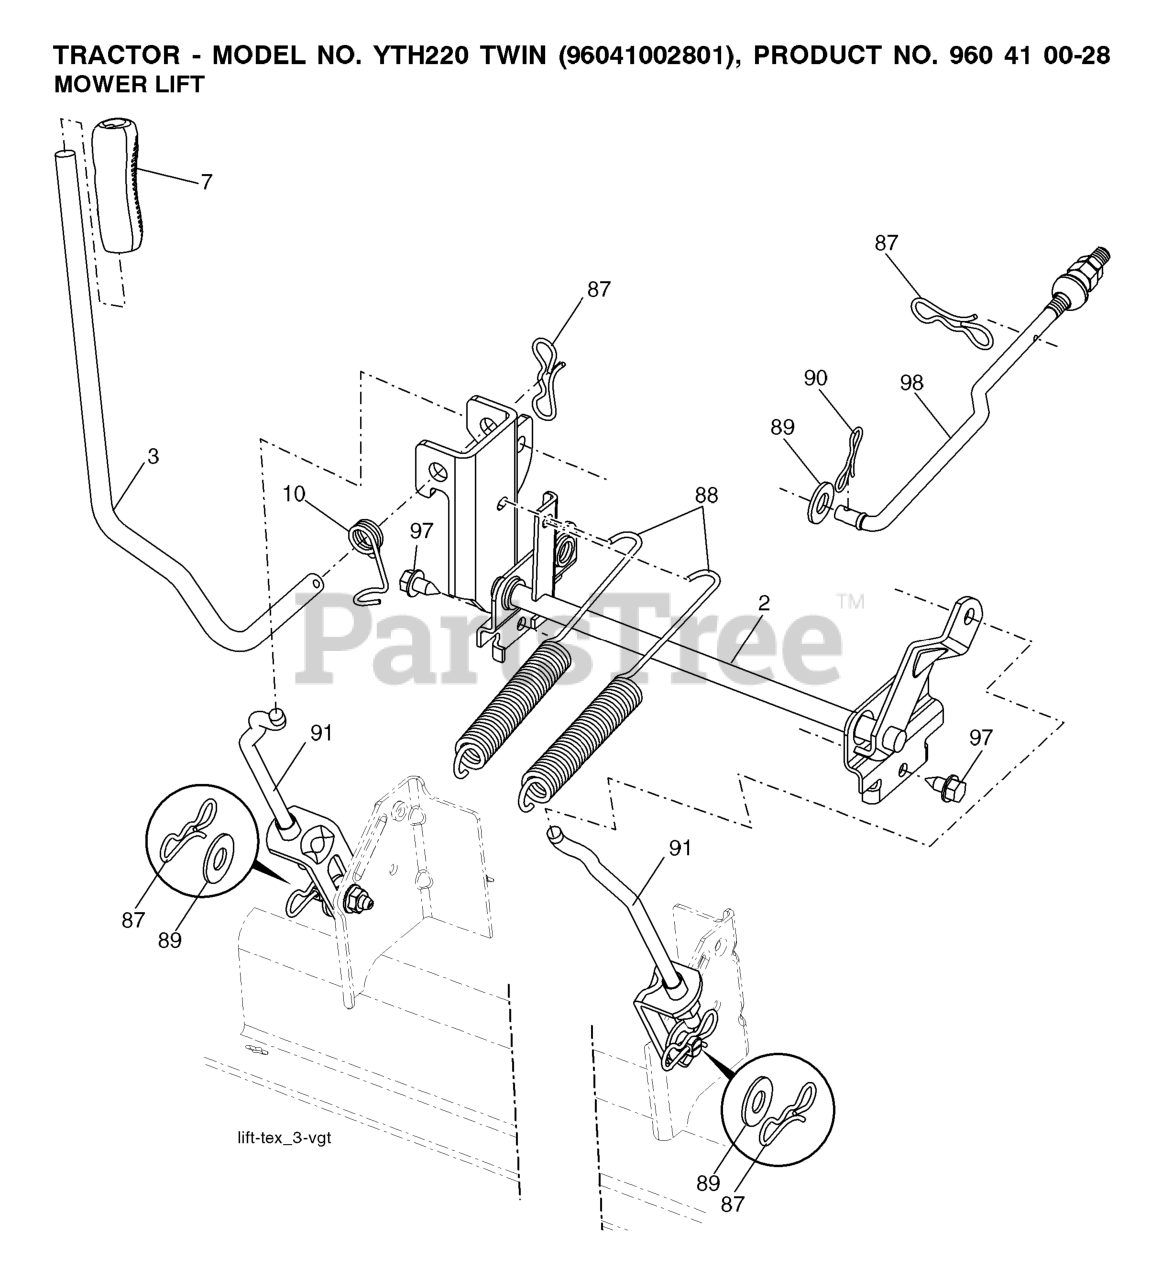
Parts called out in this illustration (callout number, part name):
2	SHAFT.ASM.LIFT.CROSS.H
3	LEVER.LIFT.HANDLE.GT
7	GRIP.HANDLE.LIFT.PVC.BLACK
10	SPRING.TORSION.LIFT.HANDLE
87	PIN.COTTER.7/16.BOW TI.
88	SPRING.LIFT.ASSIST
89	WASHER.CLEAR.ZINC
90	PIN.COTTER.5/16.BOW TI
91	LINK.ASM.LIFT.54"TG
97	SCREW, 3/8-16X3/4
98	LINK.ASM.SUSP.FRONT.MWR.10.5
